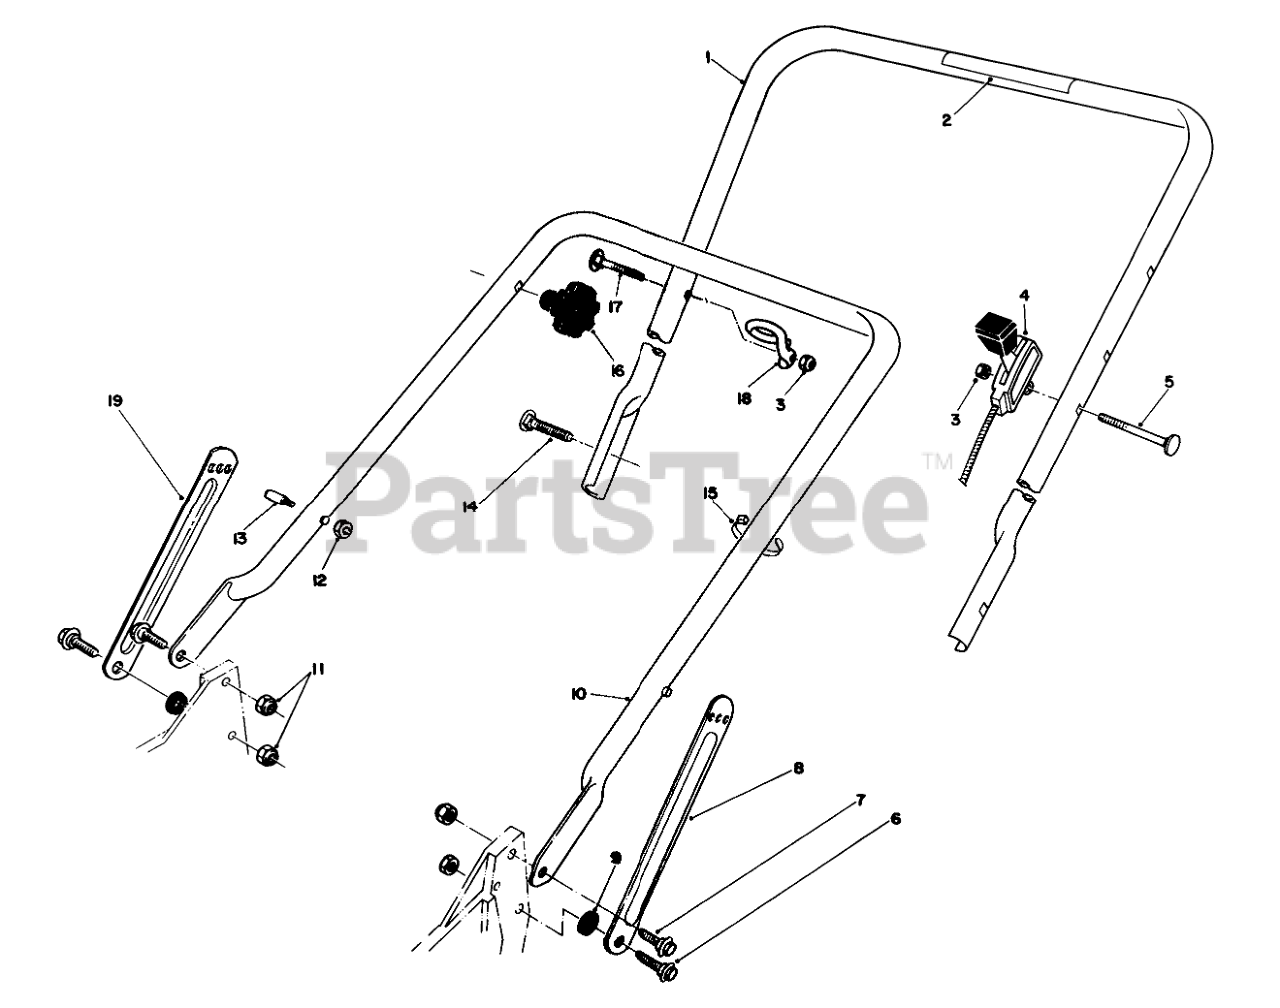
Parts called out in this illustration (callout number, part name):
1	Handle-Upper (Incl. Ref. #2)
2	WARNING DECAL
3	NUT-LOCK, NI
4	THROTTLE CONTROL
5	SCREW-HANDLE
6	SCREW-SHOULDER
7	SCREW-SHOULDER
8	LH HANDLE LATCH
9	SPACER
10	LOWER HANDLE ASM
11	NUT-LOCK, NI
12	NUT-LOCK, NI
13	HANDLE PIN
14	5/16-18 X 2 HNDLE SCREW
15	TIE-CABLE
17	HANDLE SCREW
18	Guide
19	RH HANDLE LATCH
